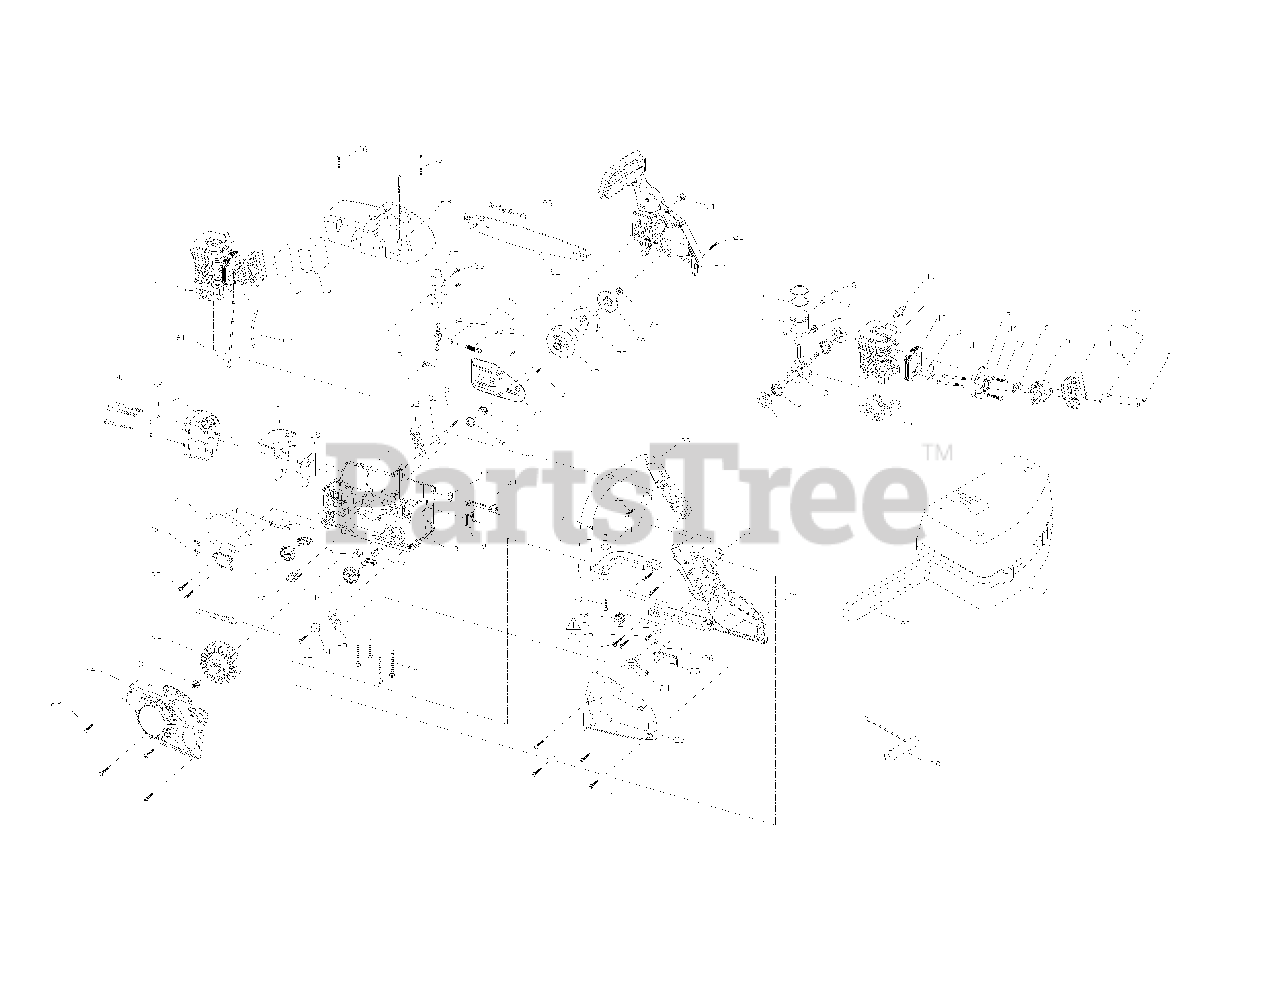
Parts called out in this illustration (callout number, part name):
1	CAP, BEARING
3	CRANK/ROD ASS'Y
5	RING, PISTON
6	ROLLER, PISTON
7	PIN, PISTON
9	CASE, CRANK
10	SPARK PLUG
12	RUBBER, ISOLATOR
15	ISOLATOR, CARBURETOR
16	SPRING WASHER
19	CARBURETOR
20	AIR FILTER ASS/Y
23	HANDLE, LEFT PART
24	TRIGGER, THROTTLE
25	TRIGGER, RELEASE
27	SCREW
29	HANDLE, REAR
33	HANDLE, FRONT
34	STARTER HOUSING ASS'Y
38	WIRE ASS'Y
39	IGNITION ASS'Y
40	CONDUCTIVE PLATE
41	OIL CAP ASS'Y
42	FIX PLATE
44	FUEL CAP ASS'Y
45	FIX PLATE
48	HOUSING ASS'Y
49	HOLDER, CABLE
50	LEVER, CHOKE (MTD BLUE)
51	HOLDER, CHOKE LEVEL
52	FIX PLATE
53	CONNECTOR
55	PUMP ASS'Y
59	MUFFLER ASS'Y
61	CABLE, THROTTLE
62	FUEL PIPE
63	WOODRUFF KEY
65	FILTER, AIR
70	SPRING WASHER
74	CAP, ANTI-DUST
76	DRUM ASS'Y
77	CLUTCH ASS'Y
78	CAP, ANTI-DUST
80	BRAKE KIT ASS'Y
85	SCREW
87	SPIKED BUMPER
90	CARRY CASE
